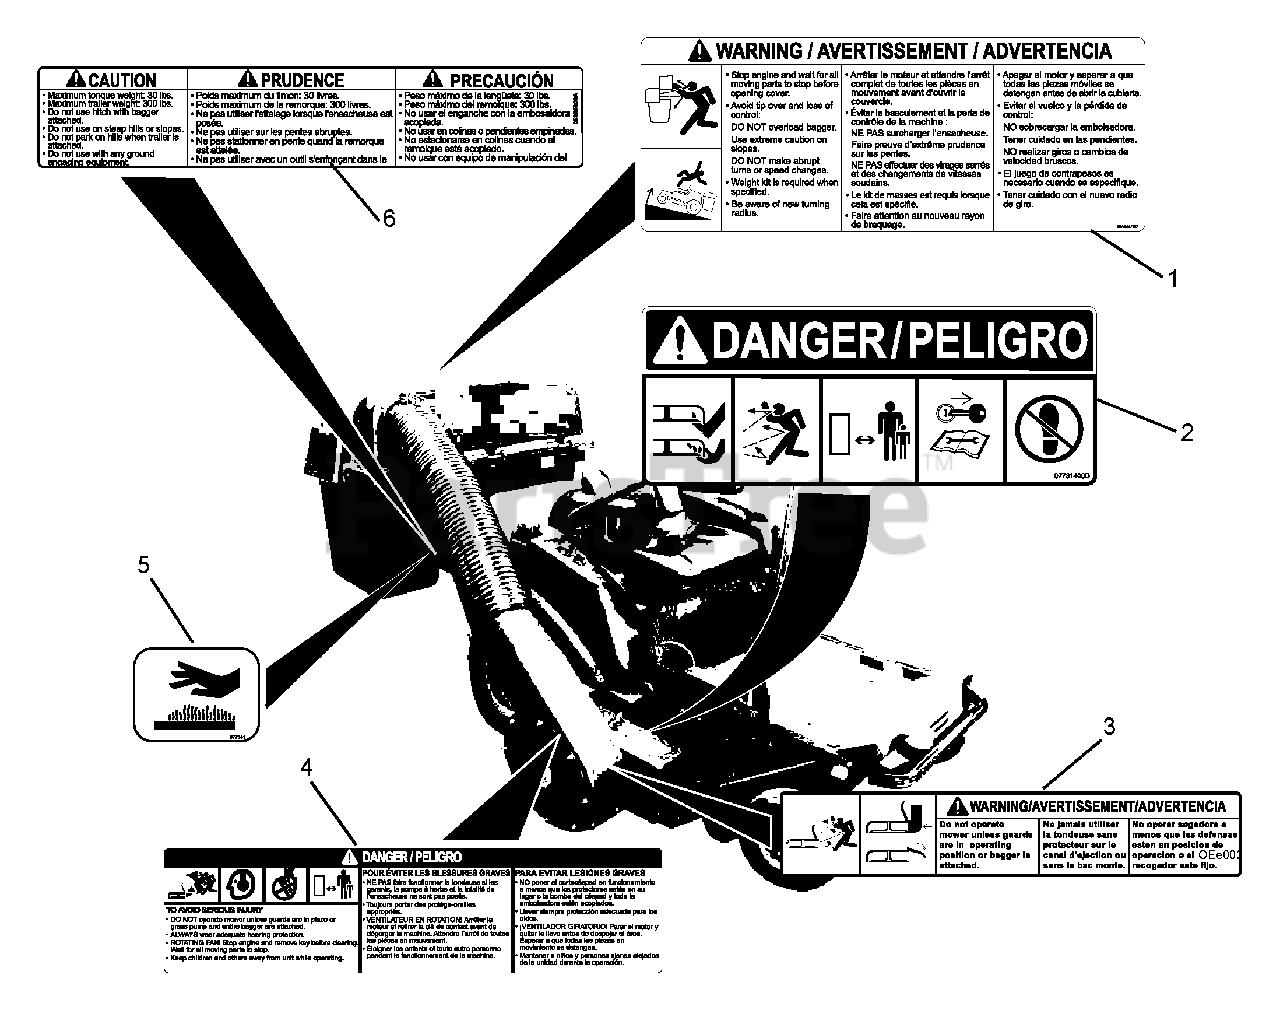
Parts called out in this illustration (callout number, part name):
1	DECAL, BAGGER COVER
2	DECAL, MOWER PAN DANGER
3	DECAL, WARNING
4	DECAL-CAUTION, GRASS PUMP
5	DECAL, HOT SURFACE
6	DECAL, TRAILER HITCH
